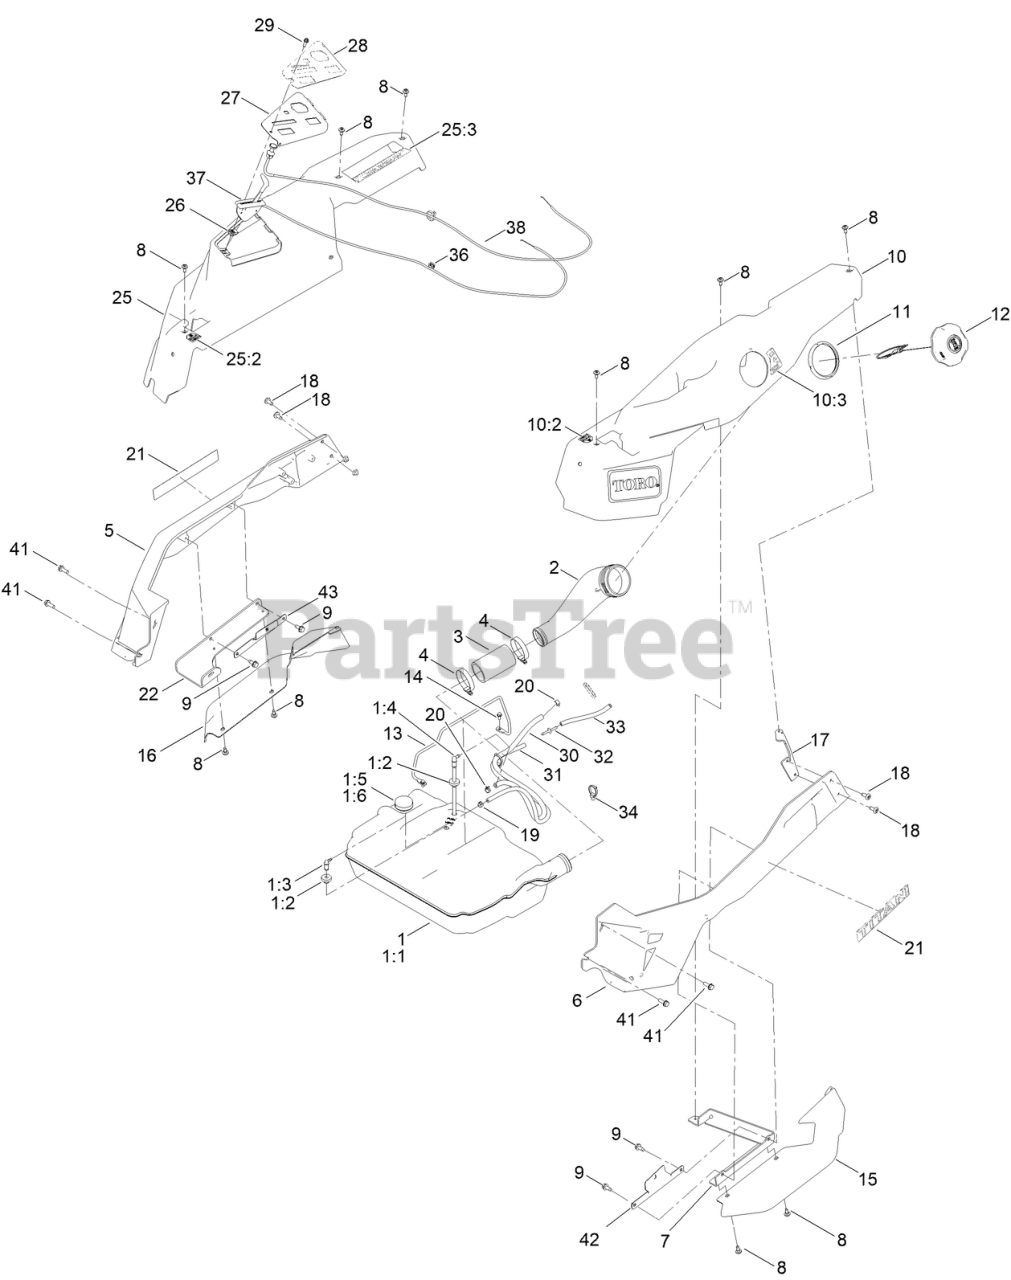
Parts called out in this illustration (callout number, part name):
1	TANK-FUEL, ASM
1:1	TANK-FUEL
1:2	BUSHING
1:3	FITTING-ELBOW 90
1:4	FITTING - PICKUP, FUEL
1:5	GROMMET-FUEL
1:6	REMOTE GAUGE ASM
2	NECK-FILLER, FUEL
3	HOSE-FILLER, FUEL
4	CLAMP-HOSE
5	CAST-TUBE, RH [RED]
6	CAST-TUBE, LH [RED]
7	MOUNT-POD BRACKET LH
8	SCREW-SHOULDER
9	SCREW-HWHTF
10	POD ASM - LH W/DECALS
10:2	DECAL-CONTROL LEVER, LH
10:3	DECAL-FUEL FILL
11	RING-RETAINING
12	CAP-FUEL, RATCHETING
13	ROD-HOLD DOWN
14	SCREW-HWH
15	FENDER-TIME CUTTER, LH
16	FENDER-TIME CUTTER, RH
17	BRACKET-REAR POD, LH
19	CLAMP-HOSE
20	CLAMP-HOSE
21	DECAL-TITAN
22	BRACKET-MR SPRING
25	POD ASM - RH , MR W/DECALS
25:2	DECAL-CONTROL LEVER, RH
27	PANEL-CONTROL
28	DECAL - CONTROL PANEL
29	SCREW-HWHTF
30	HOSE-FUEL
31	HOSE-FUEL
32	ADAPTER ORIFICE
33	HOSE-VENT
34	CLIP-TIE
36	CLIP-HARNESS
37	CABLE-THROTTLE
38	CABLE-CHOKE
41	SCREW-TAPTITE
42	BRACKET-ALIGNMENT, POD LH
43	BRACKET- ALIGNMENT, POD RH MR
